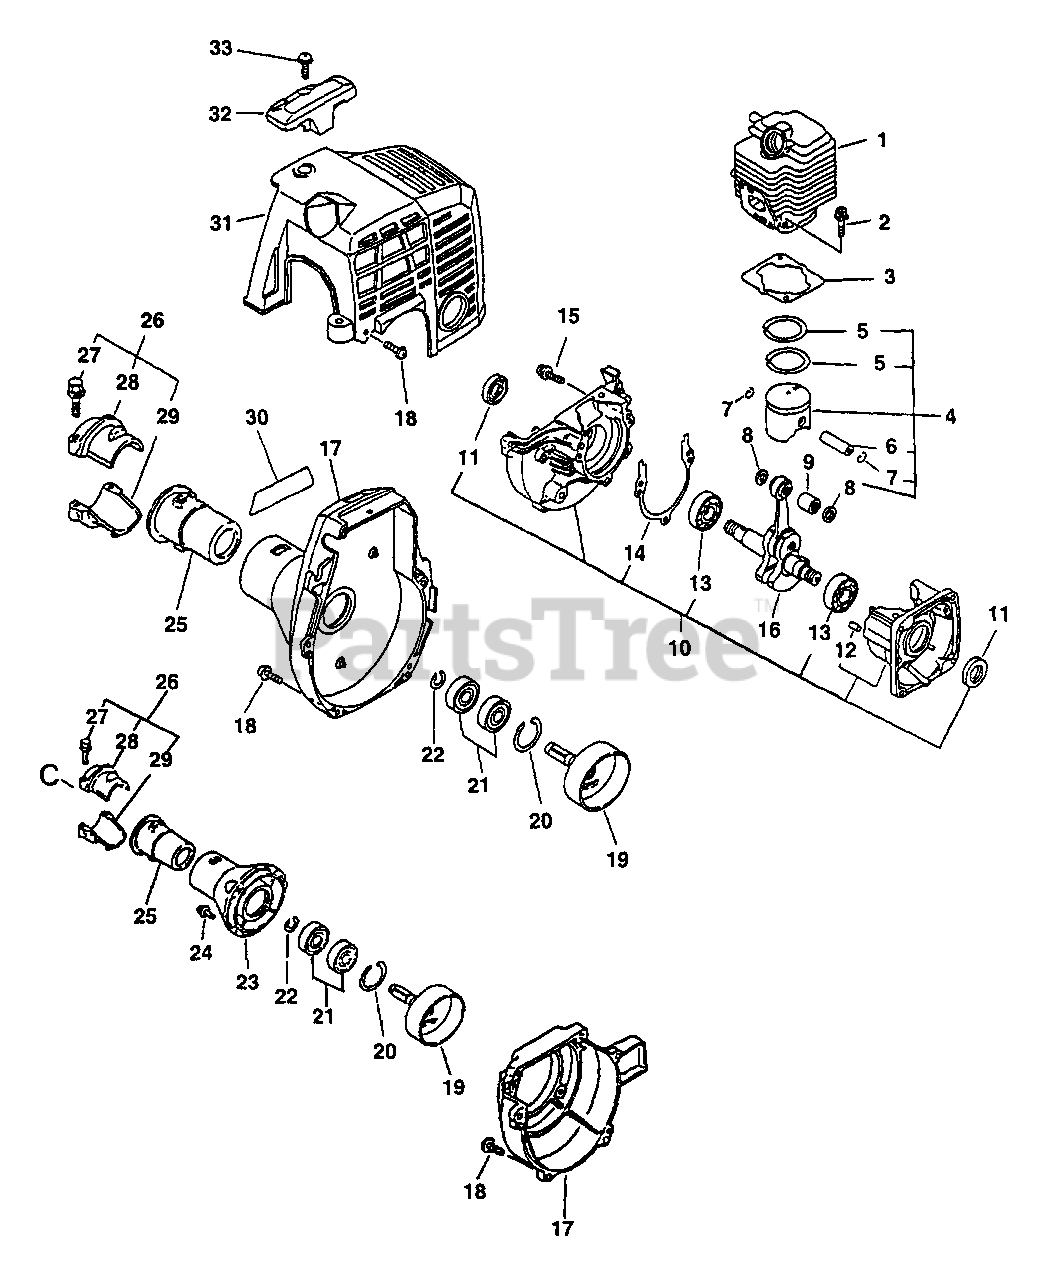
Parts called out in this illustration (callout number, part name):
1	CYLINDER
2	BOLT 5×22
3	GASKET, CYLINDER
4	PISTON KIT
5	RING, PISTON
6	PIN, PISTON 8
7	RING, SNAP
8	WASHER, THRUST
9	BEARING, NEEDLE
10	CRANKCASE KIT
11	SEAL, OIL 12
12	PIN, LOCATING 4
13	BEARING, BALL - 6201 C3
14	GASKET, CRANKCASE
15	BOLT 5×28
16	CRANKSHAFT ASSY
17	COVER, FAN - GRAY
17	FAN CASE ASSY
17	COVER ASSY, FAN
18	BOLT 4×16
19	DRUM, CLUTCH
20	RING, SNAP 28
21	BEARING, BALL 6001
22	RING, RETAINING - 12
23	CASE, CLUTCH - GRAY
24	SCREW 5×16
25	CUSHION
25	CUSHION Ø25
26	HOLDER KIT
26	RETAINER KIT
27	BOLT - 5×25
28	HOLDER, MAIN PIPE - UPPER
29	HOLDER
29	HOLDER - LOWER
30	LABEL, MODEL
31	COVER, ENGINE - GRAY
31	COVER, ENGINE
32	GUARD, TOP
33	SCREW 5×16
